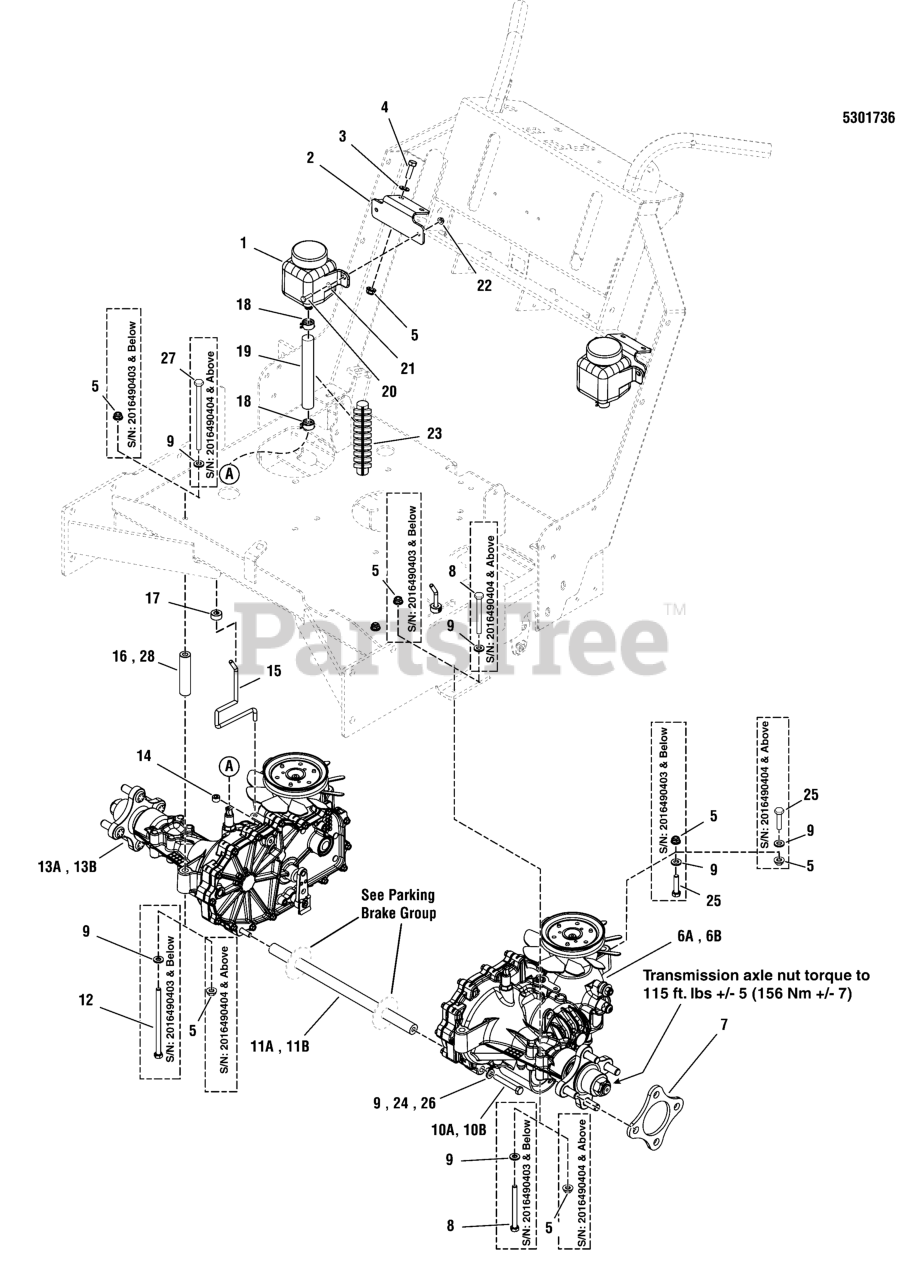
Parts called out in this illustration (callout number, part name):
1	RESERVOIR, HYDRO OIL, 350 ML
2	PLATE, HYDRO BOTTLE, MOUNT - RED
3	WASHER, 5/16" SAE
4	BOLT, 5/16-18 X 1 GD5 YZ
5	NUT, 5/16-18 HEX NYLOCK FLANGE
8	BOLT, 5/16-18 X 2-3/4, GD 5, YZ
9	WASHER, 5/16 GD.9 FLAT
12	BOLT, 5/16-18 X 5-1/2, GD 5, YZ
14	COLLAR, 1/4 SET
15	ROD, HYDRO RELEASE, SW30
16	SPACER, .34 X 1.00 X 3.27, YZ
17	COLLAR, 5/16 SET
18	CLAMP, HOSE, .75 FREE DIA.
19	HOSE, 1/2" PUSH-ON, 24.00"
20	BOLT, 1/4-20 X 3/4 GD5 YZ
21	WASHER, 1/4 SAE
22	NUT, 1/4-20 HEX NYLOCK FLANGE
23	WIRE LOOM, 3/4" ID, 20" LONG
24	WASHER, 3/8 GD.9 FLAT
25	BOLT, 5/16-18 X 2-1/4" GD5 YZ
26	WASHER-0.375(0.41IDX1.75ODX.25THK) BLK
27	BOLT, HEX, 5/16-18 X 6", GD5, CZ
28	SPACER, .34 X 1.00 X 3.02 CZ
